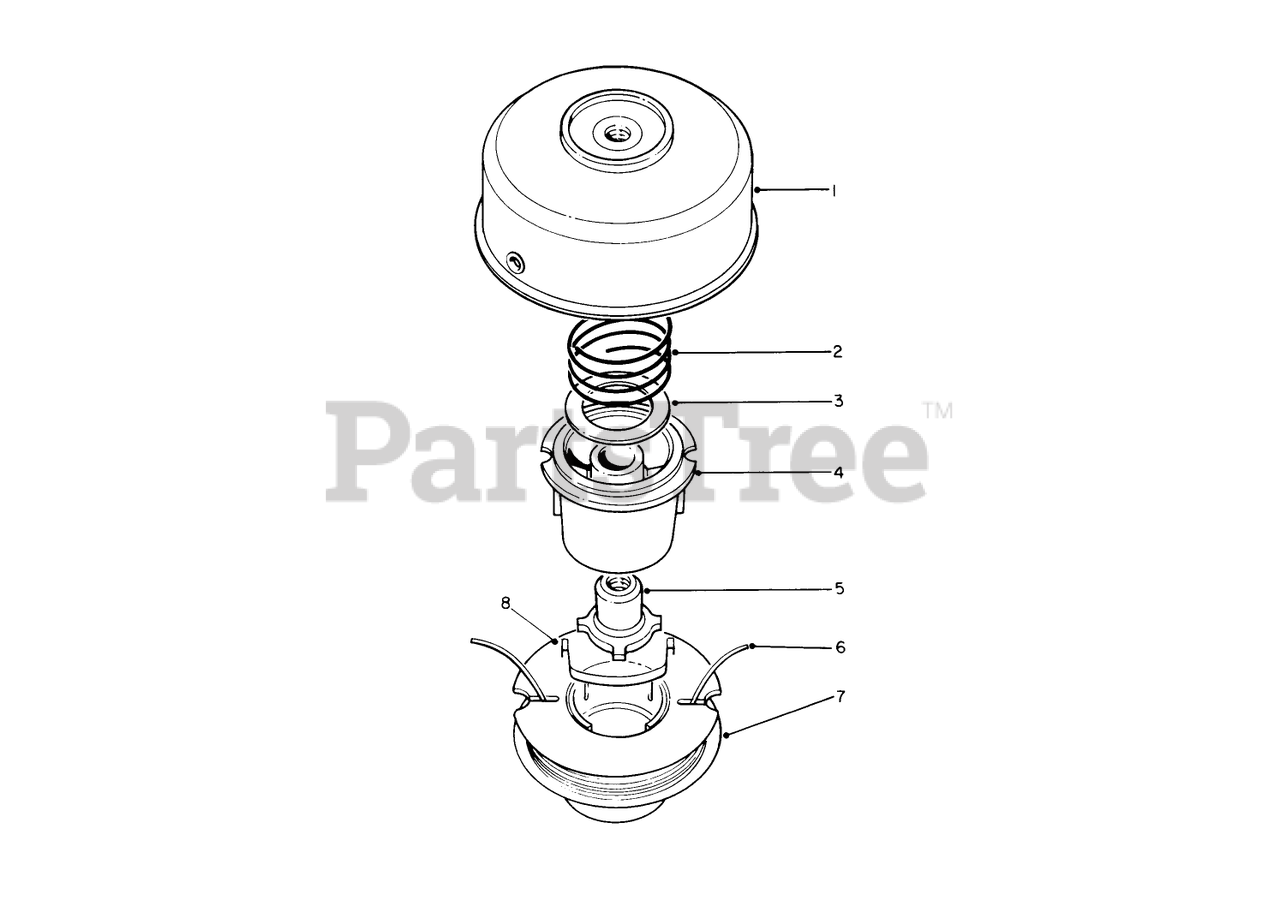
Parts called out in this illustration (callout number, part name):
2	SPRING
3	WASHER-FLAT
4	SPOOL CORE
